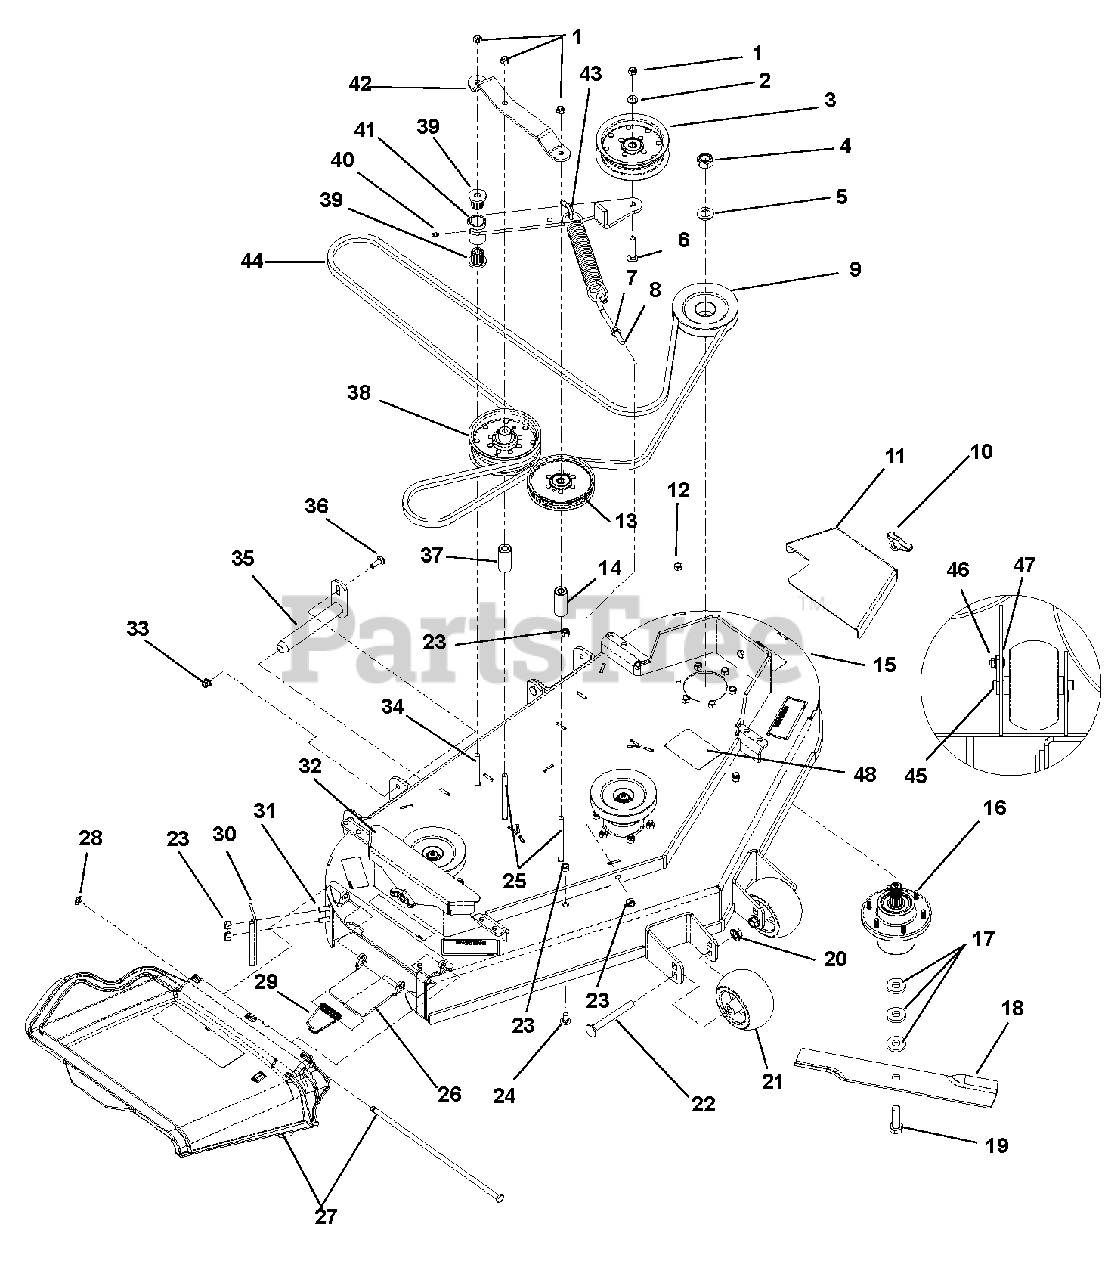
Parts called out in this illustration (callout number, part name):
1	LOCKNUT, 3/8-16 CROWN Y
2	WASHER, .406X.813X.065 FLAT Y
3	PULLEY, FLAT 5.00X.375 W/BRG
4	LOCKNUT, 3/4-16 CROWN PL
5	WASHER, .75X1.3125X.120
6	BOLT, 3/8-16X2.25 CRG 5 Y
7	LOCKNUT, 3/8-16 WHIZ Y
8	J-BOLT, 3/8-16 X 4.00 Y
9	PULLEY, SPLINE SPINDLE LSE
10	KNOB, 3/8-16 INSERT
11	COVER, BELT LH 48
12	NUT, 3/8-16 STD HEX GR5 Y
13	PULLEY, FLAT IDLER
14	SPACER, .437X1.00X2.50 SMLS
15	ASSY, DECK W/DECALS 48 GD
16	ASSY, SPINDLE HOUSING
17	WASHER, .630X1.50X.250 FLAT Y
18	BLADE, 16.500 X .80 LIFT
19	BOLT, 5/8-11 X 2.00 HEX 8 Y
20	LOCKNUT 1/2 W/FLANGE
21	WHEEL, GAGE
22	BOLT, 1/2-13X4.50 CRG 5 Y
23	LOCKNUT, 3/8-16 NYLOC Y
24	BOLT, 3/8-16X.750 CRG 5 LN Y
25	BLT-RDHDSQNK .38-16X5.0 YWZC
26	BRKT, SUPPORT DISCHARGE CHUTE
27	CHUTE DISCHARGE ASSY #
28	RETAINER #
29	SPRING, TORSION .460"X.138"
30	PLATE, EXTENDER GD DECK
31	BOLT, 3/8-16X1.00 CRG 5 SN Y
32	COVER, BELT RH 48
33	LOCKNUT, M8X1.25 NYLOC FLG 10Y
34	BOLT, 3/8-16X3.50 CRG 5 Y
35	PIN, WELDED
36	BOLT,RH,SQNECK,JDS137,M8X1.25X
37	SPACER, .437X1.00X2.25 SMLS
38	PULLEY, FLAT 5.25X.375 W/BRG
39	BRG, FLG M10XM25XM27 FLUTED
40	FTG, 1/4-28 STRGT GREASE ZERK
41	ARM, IDLER *
42	STRAP, IDLER PULLEY
43	SPRING, DECK IDLER
45	PIVOT, RETAINER WELD
46	NUT-1/4" FLANGE PREVAILING TOR
47	BOLT, 1/4-20X.750 CRG 5 Y
48	DECAL, BELT PATH (48,52,61)
